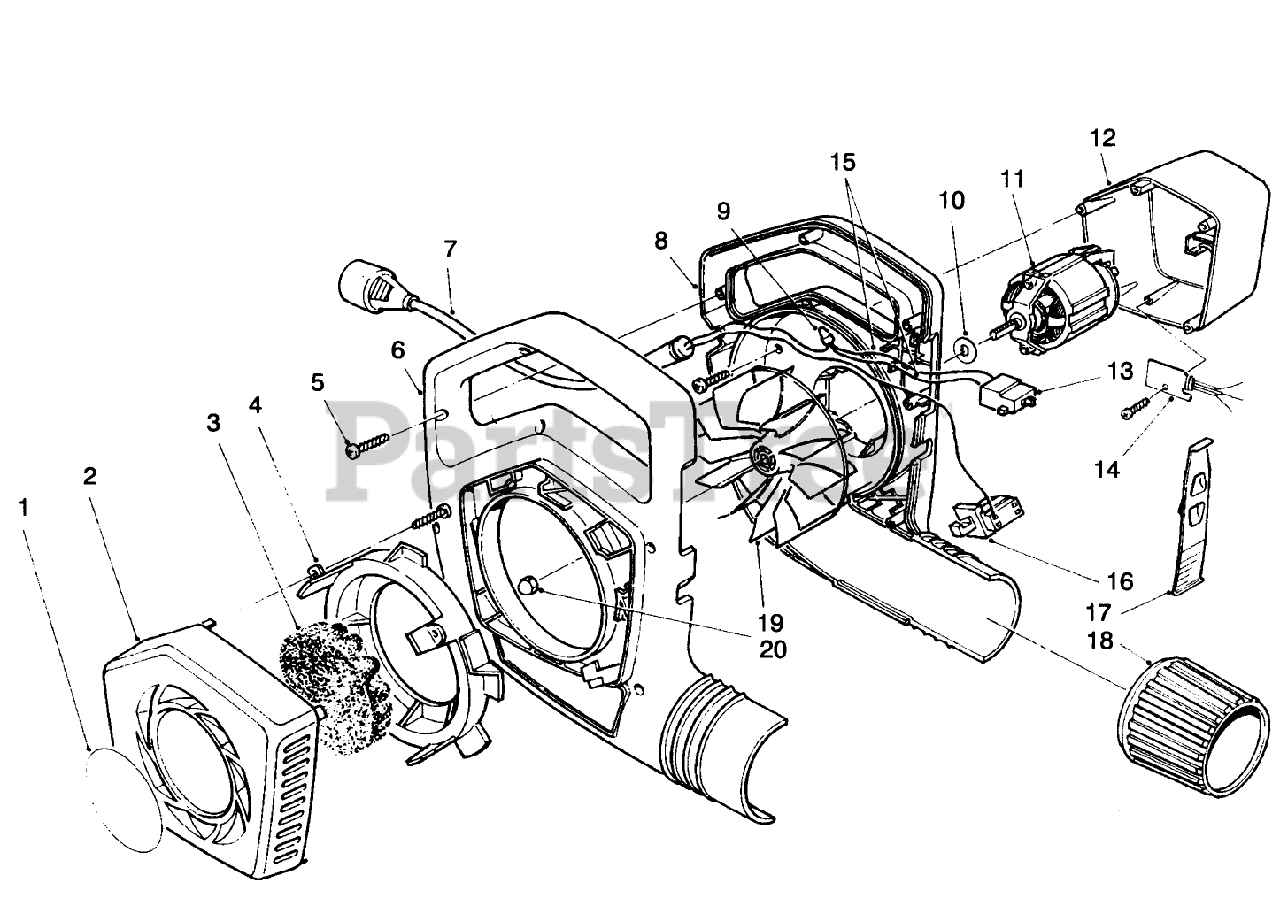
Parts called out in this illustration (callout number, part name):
1	DECAL, COVER
2	INTAKE COVER, 850 BV
3	CENTER FOAM
4	Ring-Coupling
5	Screw
6	Housing-Blower,R.H.
7	POWER SUPPLY CORD 9.5
8	BLOWER HOUSING, LH
9	Connector
10	WASHER, FAN
11	Motor-Blower
12	MOTOR COVER,850 HOTSTAM
13	Switch-2 Speed
14	DIODE ASSEMBLY
15	WIRE, 3 INCH
16	SWITCH-INTERLOCK
17	CAM SWITCH-HOT STAMPED
18	BV-OUTPUT COLLAR
19	IMPELLER, 850 BLOWER
20	NUT-HEX
